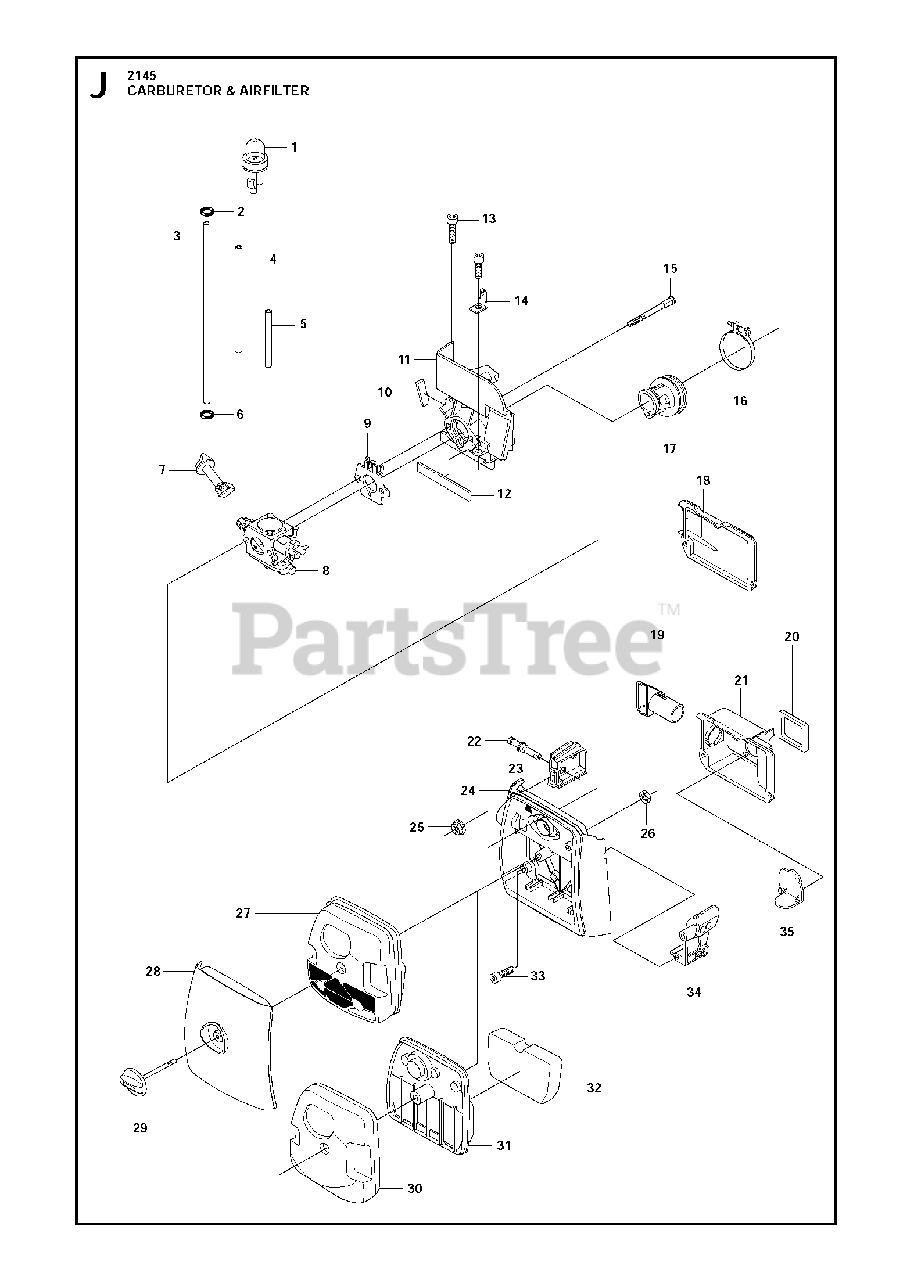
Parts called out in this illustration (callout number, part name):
1	AIR PURGE BUBBLE
3	FUEL HOSE
4	HOSE
5	NOSE
7	CHOKE CONTROL
8	CARBURETOR
9	SPACER WASHER
11	PARTITION
16	CLAMP
18	COVER
19	AIR CONDUCTOR
20	SEAL
21	AIR CAN
24	FILTER HOLDER
26	NUT M6M M5
27	AIR FILTER
28	AIR FILTER COVER
29	HANDLE AIR FILTER COVER
30	COVER
31	BASE
35	COVER
